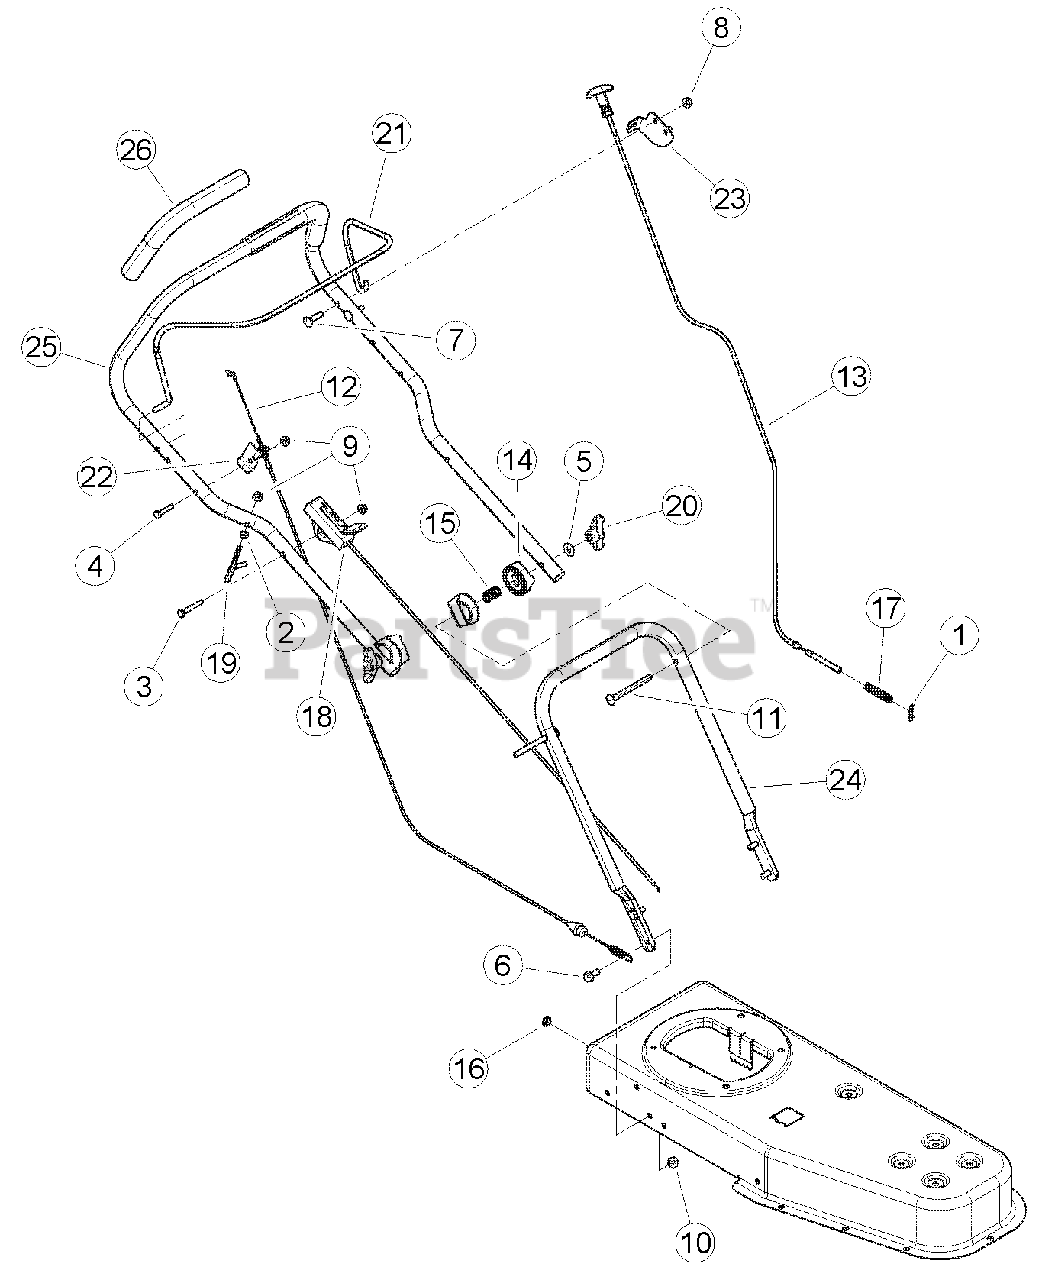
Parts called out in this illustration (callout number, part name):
1	CLIP, #13 HAIRPIN ZP
2	NUT, 1/4-20 SERR FLANGE NC ZP
3	BOLT, 1/4 X 1-3/4 HEX GR5 ZP
4	BOLT, 1/4 X 1-1/4 HEX GR5 ZP
5	WASHER, 5/16 FLAT ZP
6	BOLT, 5/16 X 3/4 SERR FLANGE UNC
7	BOLT, 5/16 X 1-1/4 CRG
8	NUT, 5/16 SPIRAL LOCK
9	NUT, 1/4-20 NYLOCK FLANGE
10	NUT, 5/16-18 NYLOCK FLANGE
11	BOLT, 5/16-18 X 3-1/2 CRG LONG NECK GR5 ZP
12	CABLE, TRIMMER ENGAGEMENT
13	CONTROL, TILT ADJUSTMENT
14	RETAINER, HANDLEBAR ADJUSTMENT
15	SPRING, RETAINER COMPRESSION
16	GROMMET, 3/8 ID X 5/8 OD
17	SPRING, TILT CONTROL COMPRESSION
18	CONTROL, THROTTLE
19	GUIDE, RECOIL ROPE
20	KNOB, 5/16-18 FEEM TEE
21	BAIL, CONTROL
22	BRACKET, CABLE ANCHOR
23	BRACKET, HEIGHT ADJUSTMENT ANCHOR
24	SUPPORT, TRIMMER HANDLE
25	ASSEMBLY, TRIMMER HANDLE BAR, SERVICE PART
26	PAD, FOAM HANDLEBAR (32022-00)
